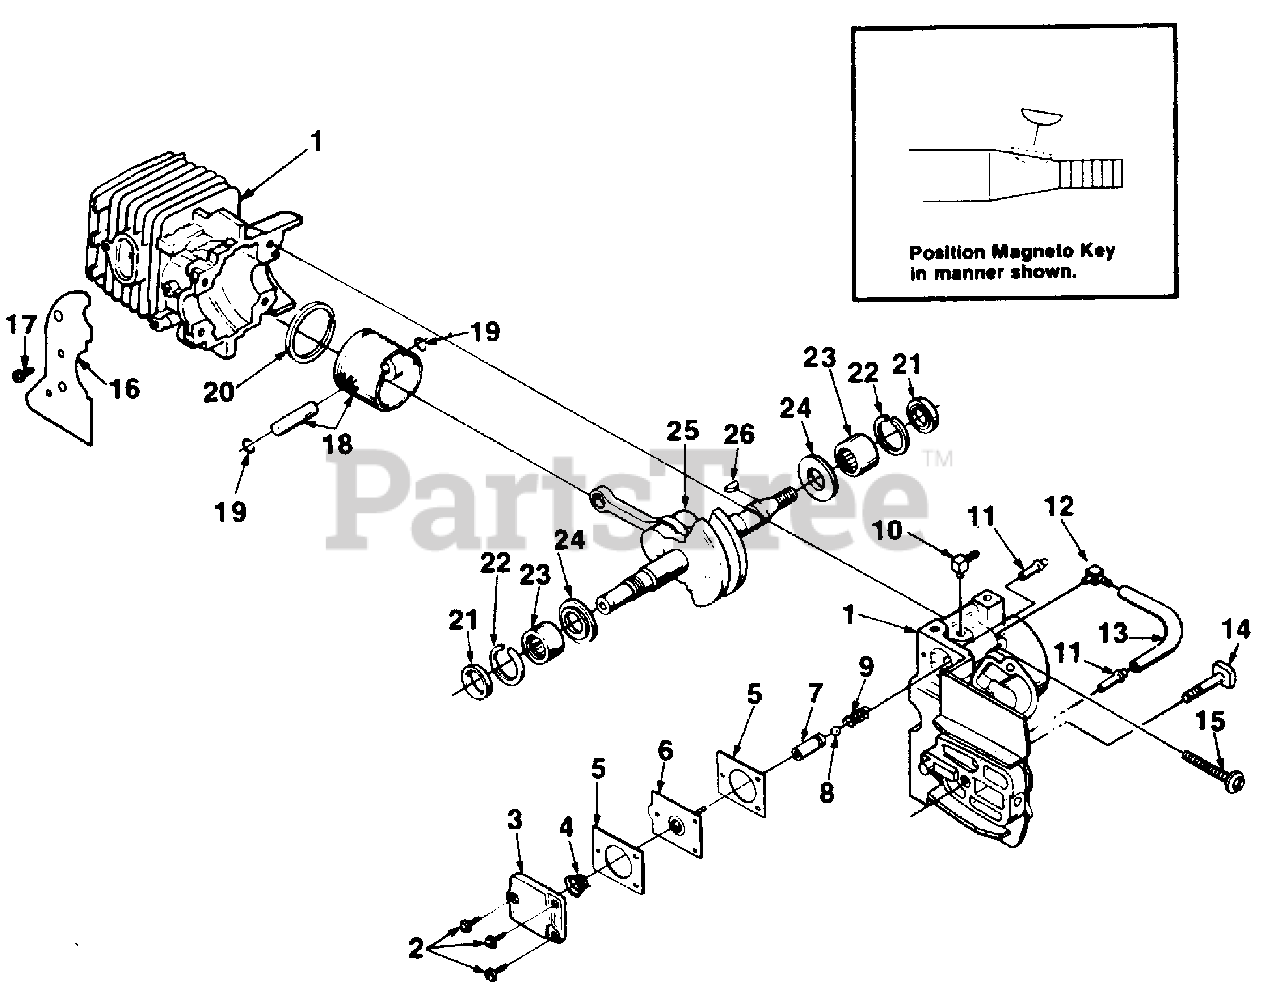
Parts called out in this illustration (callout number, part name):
1	CRANKCASE & CYLINDER ASSY.
2	SCREW- Pan hd. (6-32 x 3/8)
3	COVER- Oil pump
4	SPRING- Oil pump
5	GASKET- Oil pump
6	PLUNGER- Oil pump
7	BODY- Oil pump
8	BALL- Check valve
9	SPRING- Check valve
10	FITTING- Oil line
11	FITTING- Tube
12	FITTING- Oil line
13	LINE- Oil
14	BOLT- Guide bar
15	SCREW- Sems hex hd. (8-32 x 1)
16	SHIELD- Sawdust
18	PISTON & PIN ASSEMBLY
19	RING- Piston pin retaining
20	RING- Piston (primary source)
21	SEAL
22	SPACER
23	BEARING- Needle
24	WASHER- Thrust
25	CRANKSHAFT
26	KEY- Magneto
